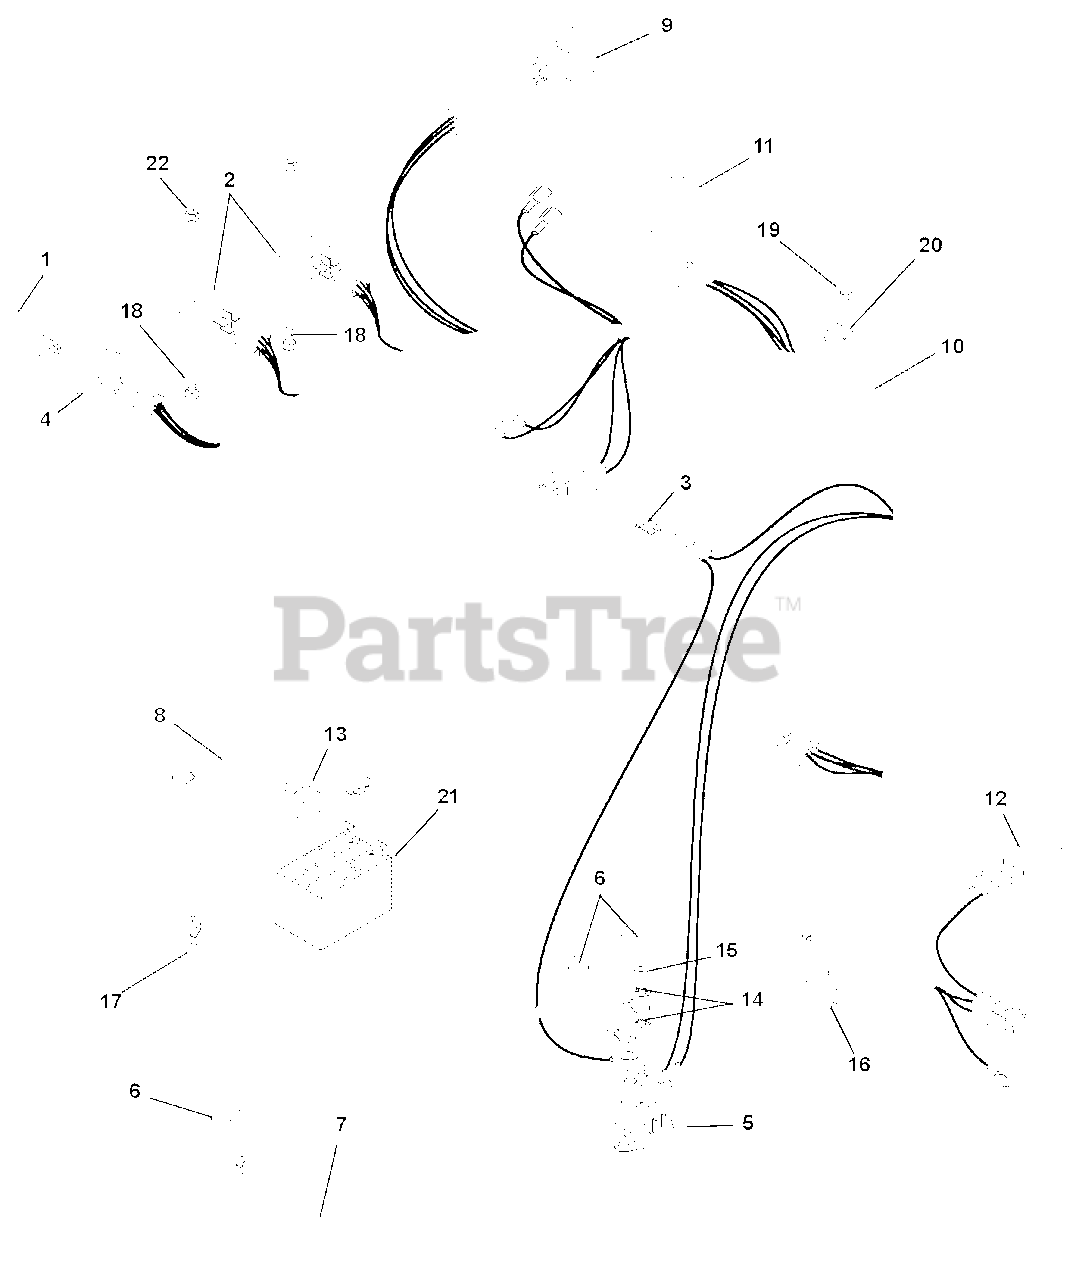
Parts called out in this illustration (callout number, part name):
1	Key with Cap
2	Relay
3	Fuse, 30 AMP
4	Key Switch
5	Solenoid
6	Boot, Eyelet Terminal
7	Starter Cable
8	Cable, Ground .25 x 13.00 x .31
9	Switch, Clutch With Retainer
11	Switch, Double Pole N.O. / N.O.
12	Diode, Connector Shell
13	Insulator
14	Washer, Locking .31
15	Nut, Jam .31-24
16	Cable Tie
17	Starter Cable
18	Screw, Hex Washer Head Machine 10-24 x .75
19	Screw, Tapping Hex Washer Head Thread Rolling .38-16 x .50
20	Clamp, Cushioned Steel .75
21	Battery, 215 CCA GEP
22	Nut, Nylon Locking 10-24
